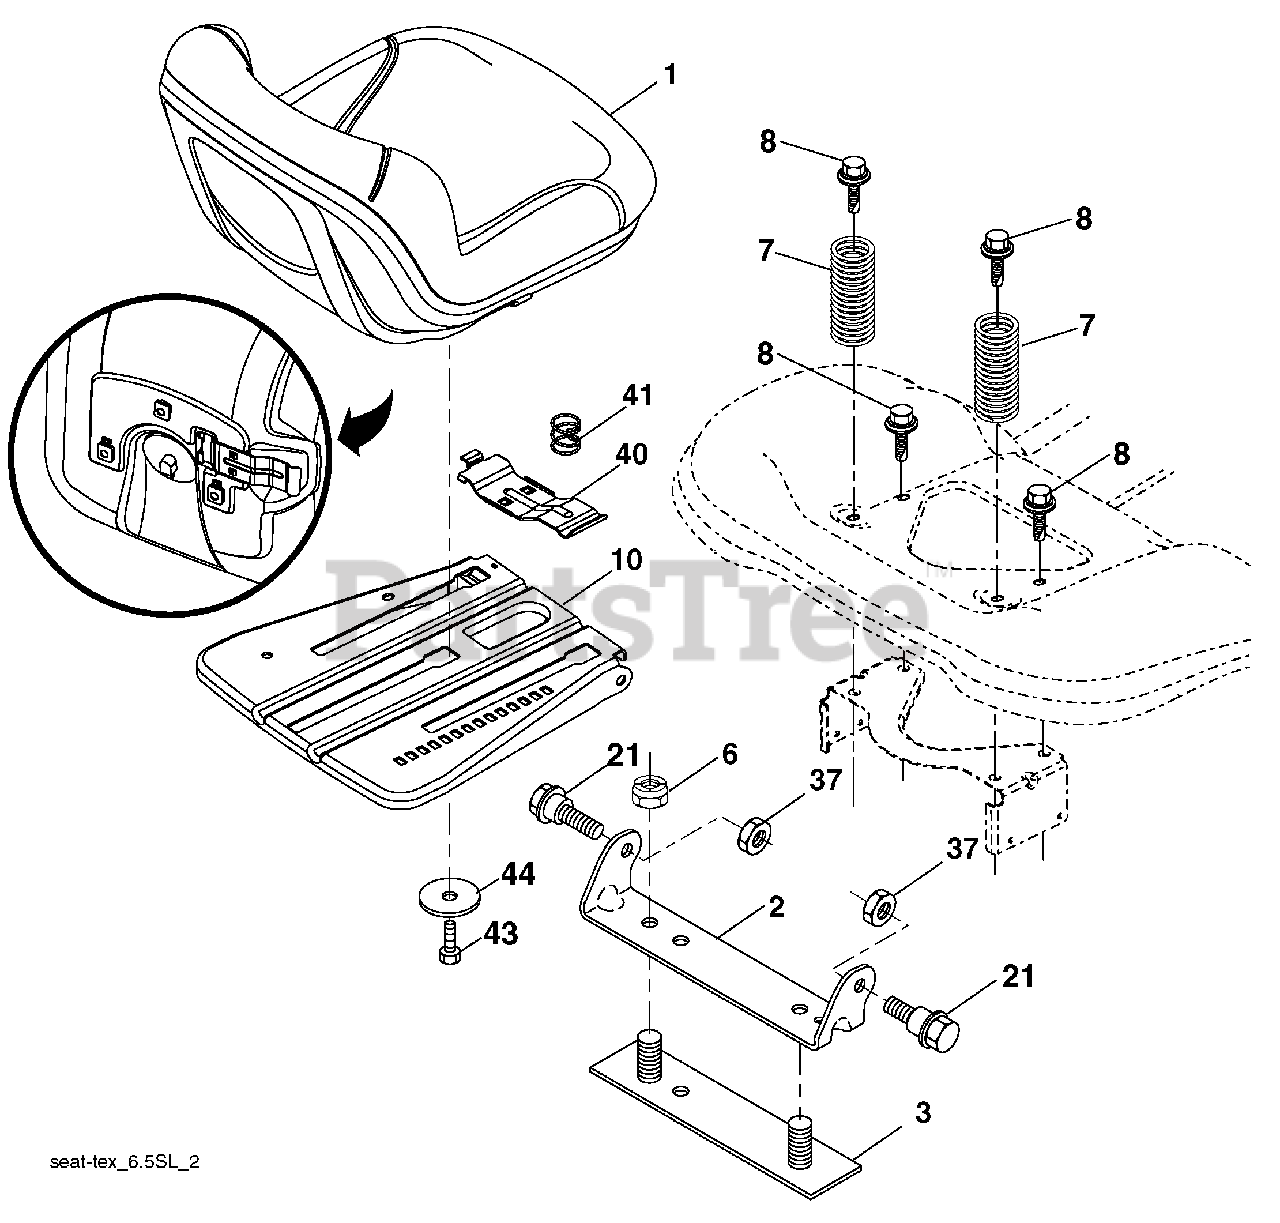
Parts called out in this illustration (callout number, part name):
1	Seat
2	Bracket Pivot Fender
3	Strap, Asm Fender
6	Nut, Lock w/Ins. 3/8-16 unc
7	Spring, Seat Cprsn
8	Bolt 5/16-18 unc x 3/4 w/Sems
10	Pan, Seat
21	Bolt, Shoulder 5/16-18
37	Nut, Lock 5/16-18 unc
40	Handle Slide
41	Spring Latch
43	Bolt 3/8-16 unc x 3/4
44	Washer 13/32 x 2 3/8 x 12 Ga.
